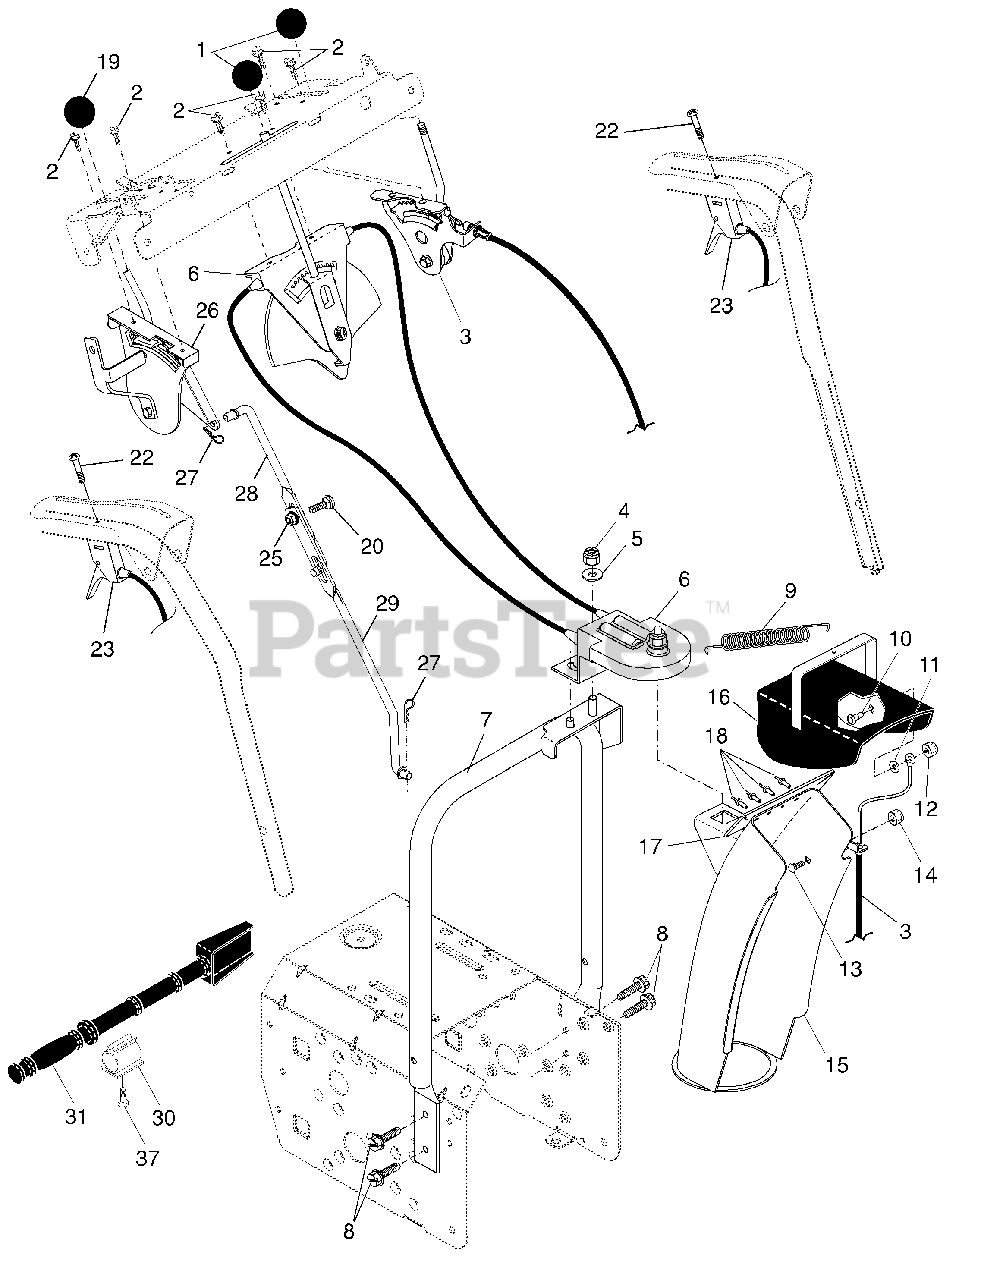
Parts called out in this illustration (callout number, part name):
1	Knob, Lever
2	Screw #10-24 x 5/8
3	Control Assembly, Defl ector
4	Nut, Lock 3/8-16
5	Washer, Flat 3/8
6	Control Assembly, Chute Rotater
7	Support, Pivot
8	Screw, Hex Head 5/16-18 x 3/4
9	Spring, Defl ector
10	Bolt, Shoulder
11	Washer, Friction, Nylon
12	Nut, Lock 1/4-20
13	Bolt, Carriage 5/16-18
14	Nut, Hex, Flanged
15	Chute Assembly
16	Defl ector Assembly
17	Seal, Defl ector
18	Rivet, Blind
19	Knob, Speed Control Lever
20	Bolt, Carriage 5/16-18 x 3/4
22	Screw #10-24 x 1-1/2
23	Control Assembly, Power Steering
25	Nut, Lock 5/16-18
26	Lever Assembly, Speed Control
27	Retainer, Hairpin
28	Rod, Upper, Speed Control
29	Rod, Lower, Speed Control
30	Clamp, Clean-Out Tool
31	Tool, Clean-Out
32	Bracket, Shift, Hydro
35	Washer, Friction
